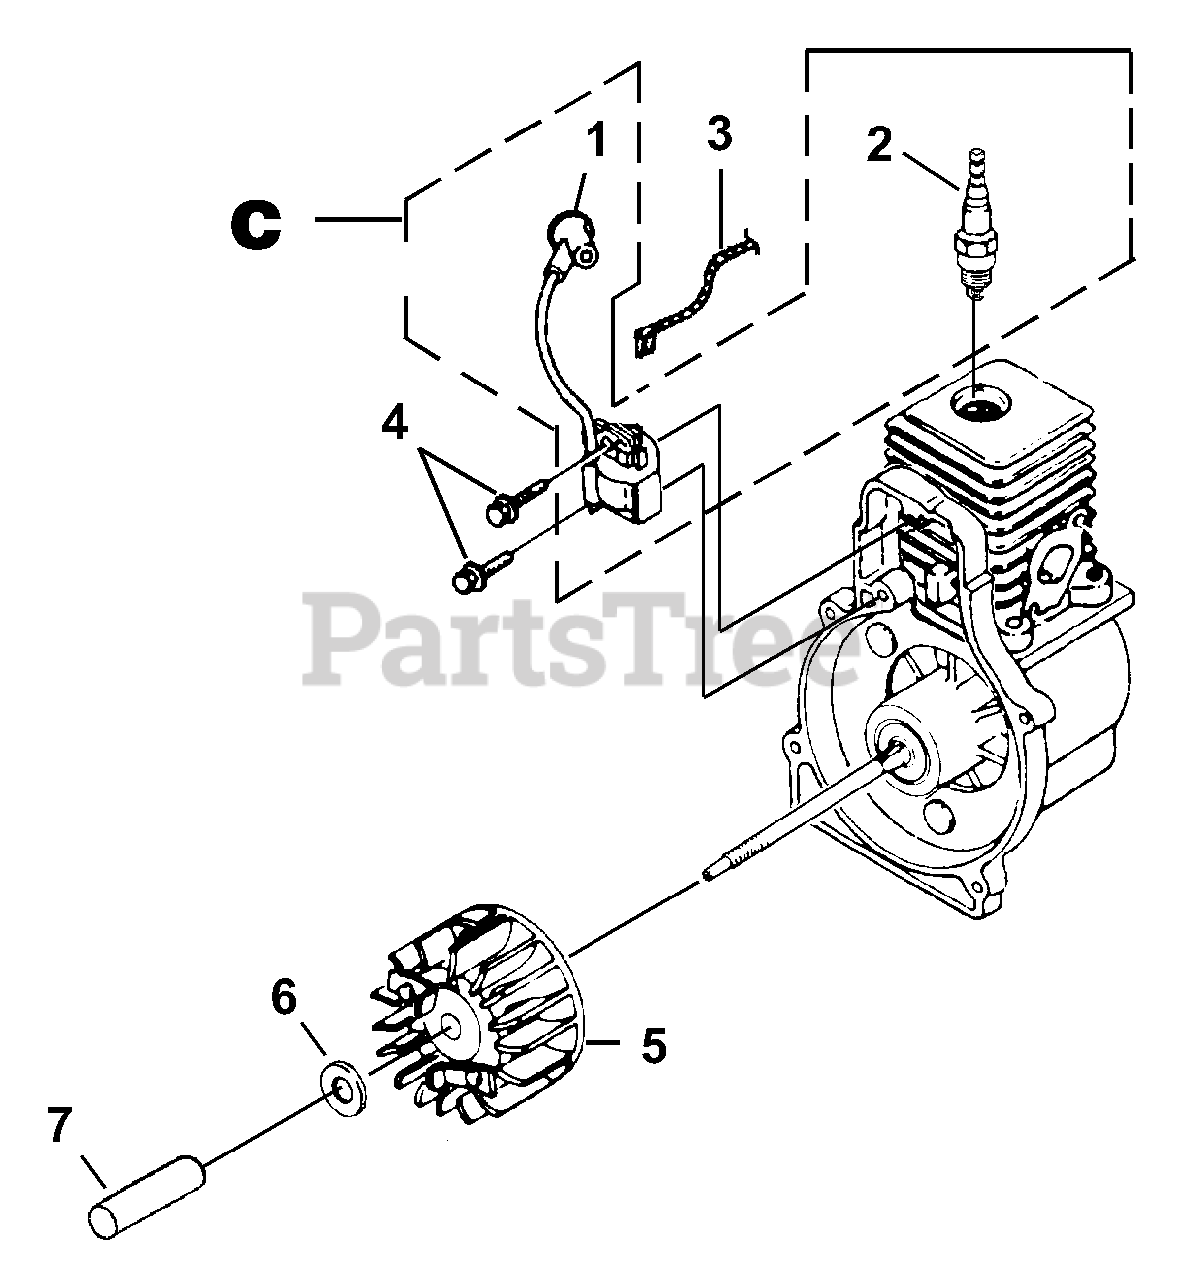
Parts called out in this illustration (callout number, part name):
1	TERMINAL-Hi-Tension
2	SPARK PLUG
3	CABLE-Throttle w/Ignition Leads (Back Packer)
4	SCREW-Thread Form. (8-32 x 1")
5	ROTOR & STARTER PAWLS
6	WASHER-Flat
7	SPACER-Fan
C	IGNITION KIT w/ Module
